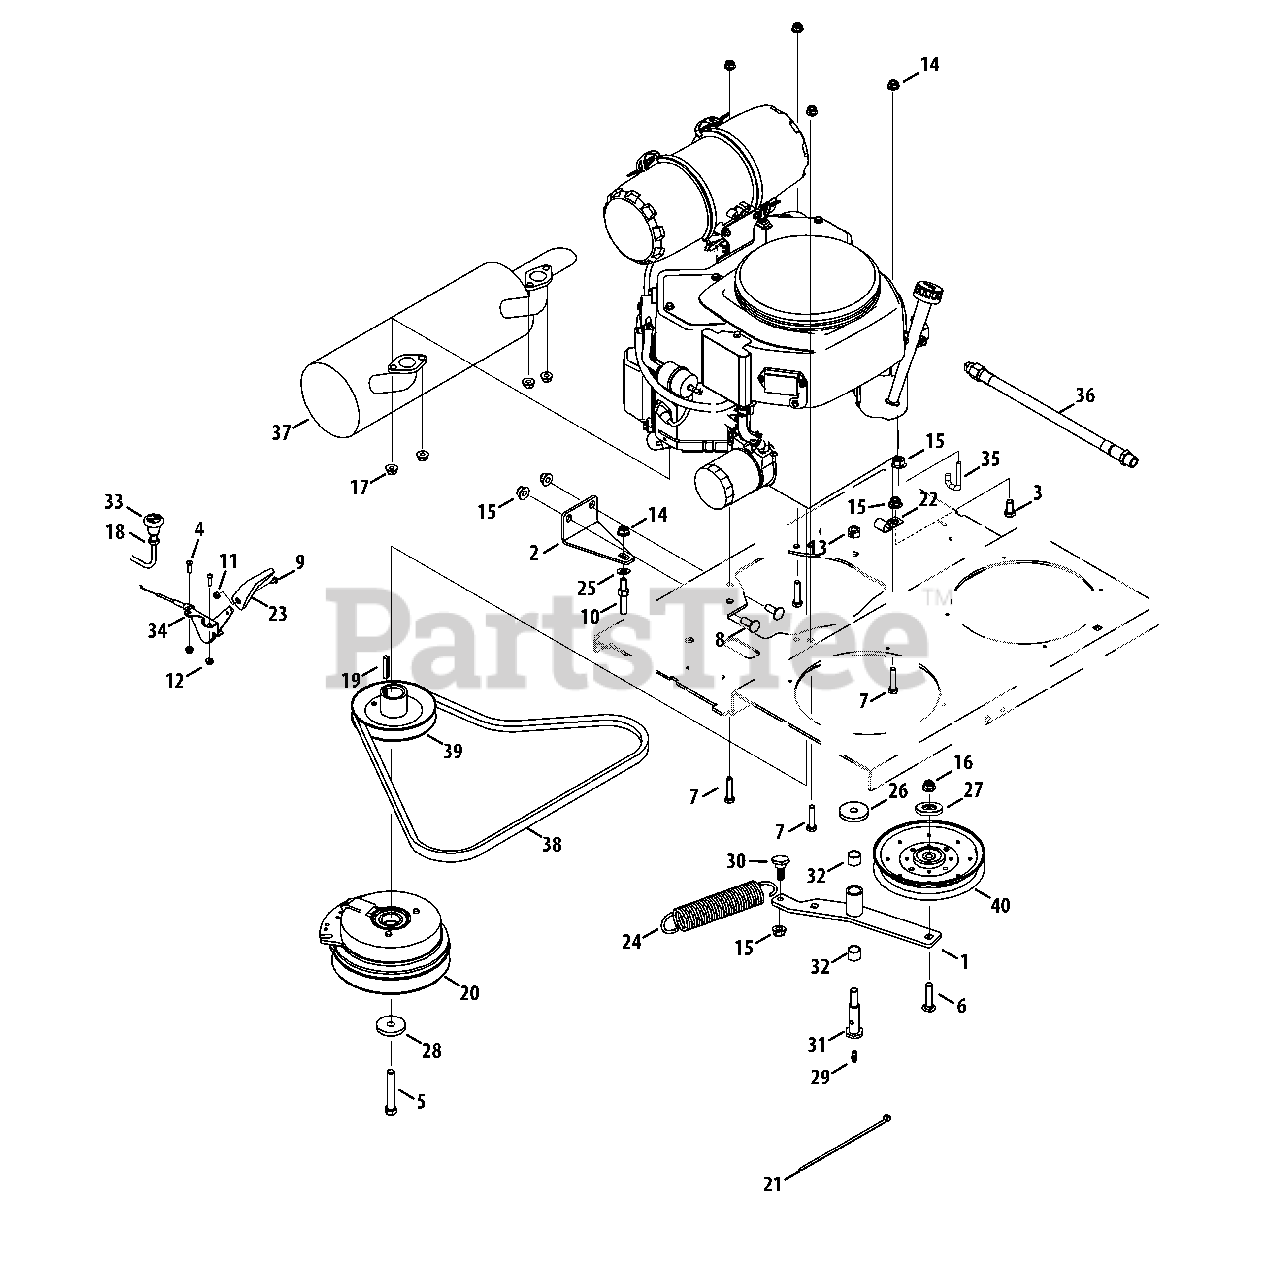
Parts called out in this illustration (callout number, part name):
1	Idler Bracket
2	Clutch Retainer Bracket
3	Hex Cap Screw, 3/8-16 x .75
4	Screw, #10-24 x .625
5	Hex Cap Screw, 7/16-20 x 2.75
6	Carriage Bolt, 3/8-16 x 1.00
7	Hex Cap Screw, 5/16-18 x 1.50
8	Carriage Bolt, 3/8-16 x 1.00
9	Screw, #8-32 x .375
10	Stud, Pivot Ball Joint
11	Nut, #8-32, Hex
12	Nut, #10-24, Hexlock
13	Nut, 7/16-14, Hexlock
14	Nut, 5/16-18, Flangelock
15	Nut, 3/8-16, Flangelock
16	Nut, 3/8-16, Flangelock
17	Nut, M8-1.25, Hexlock
18	Jam Nut, 3/8-24
19	Key, 1/4 x 1.50
20	Electric PTO Clutch
21	Cable Tie
22	Clip, .407 x 1.80
23	Throttle Control Knob
24	Extension Spring, 1.5 x 7.5
25	Washer, .344 x .688 x .065
26	Washer, .471 x 1.50 x .225
27	Pulley Cap
28	Washer, .471 x 1.50 x .225
29	Grease Fitting
30	Shoulder Screw, .625 x .302, 3/8-16
31	Shoulder Bolt, .625 x 1.947, 7/16-14
32	bearing, .638 x .753 x .615
33	Choke Control Cable
34	Throttle Cable
35	Transmission Spring Hook
36	Oil Drain Hose
37	Muffler
39	Drive Pulley
40	Idler Pulley
